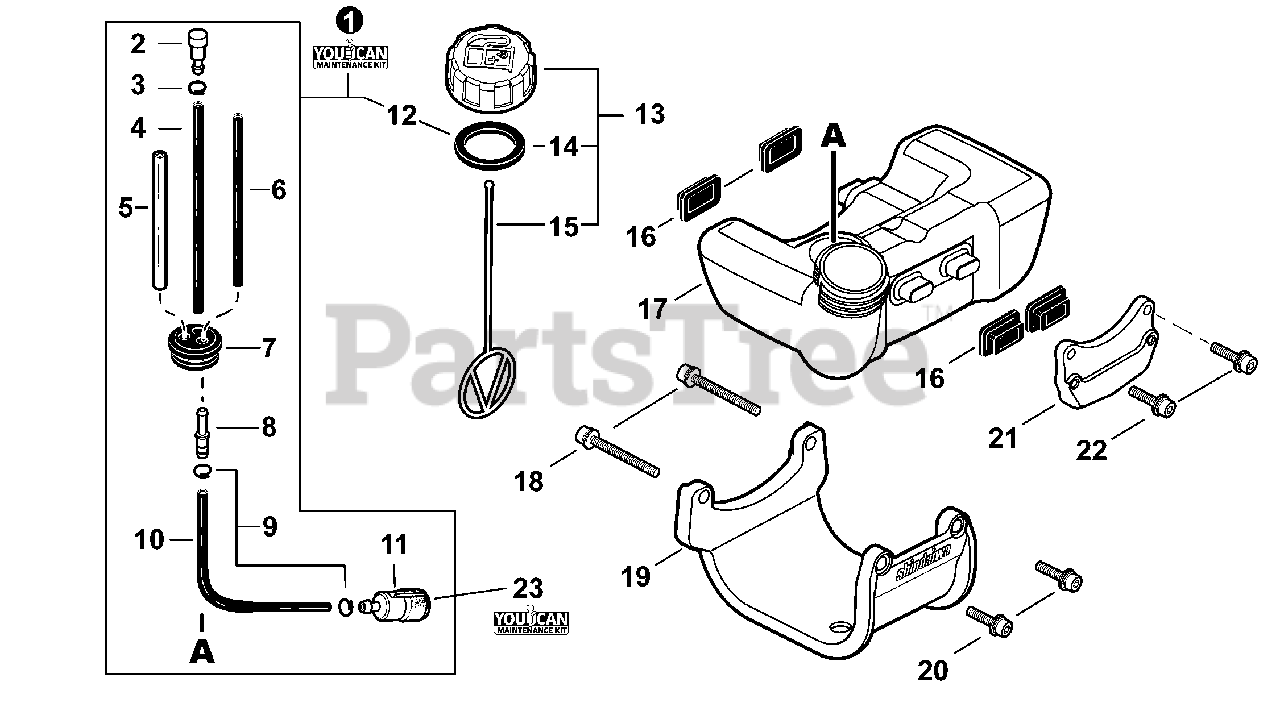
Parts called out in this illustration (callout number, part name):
1	FUEL SYSTEM KIT - YOUCANT
2	VENT ASSY
3	CLIP Ø6.5 MM
4	PIPE 3×6×115 BLACK
5	PIPE, FUEL RETURN 3×6×90 MM CLEAR
6	PIPE, FUEL 3×5×78 BLACK
7	GROMMET, FUEL
8	CONNECTOR, PIPE Ø5ר3.5
9	CLIP Ø6
10	PIPE, FUEL 3×6×120 BLACK
11	FILTER, FUEL
12	GASKET, FUEL CAP
13	CAP ASSY, FUEL
14	GASKET, FUEL CAP
15	CONNECTOR, CAP L= 123
16	CUSHION, FUEL TANK
17	TANK, FUEL
18	BOLT M5×40
19	GUARD, PLASTIC FUEL TANK
20	BOLT 5×20
21	BRACKET, METAL FUEL TANK
22	BOLT, ADHESIVE M5×20
23	TUNE-UP KIT - YOUCANT
